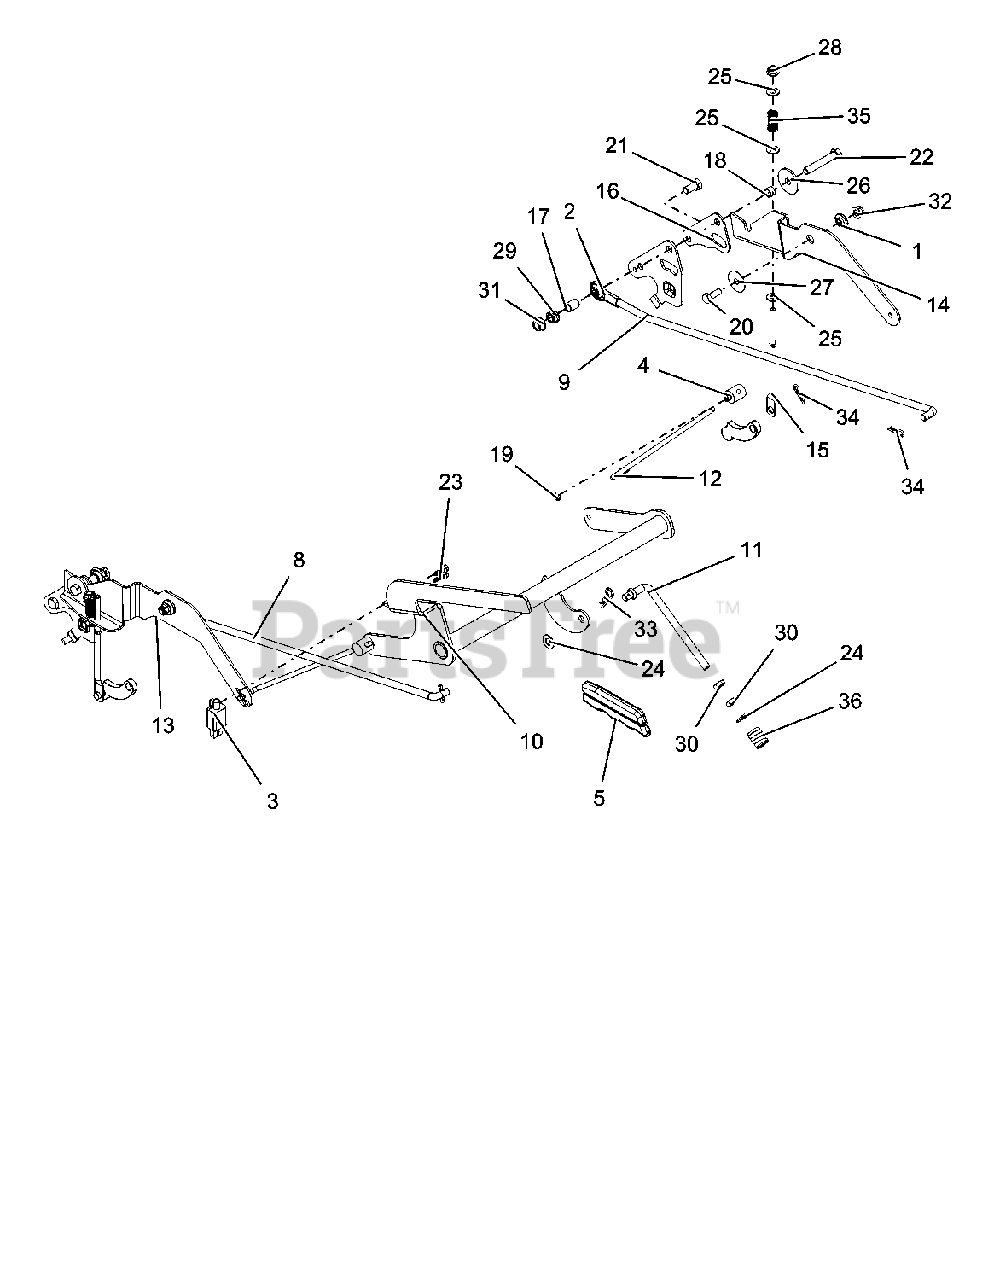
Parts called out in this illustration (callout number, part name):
1	BSHG, FLG .325X.499X.26X.88
2	ROD END, .38 RH
3	SWITCH- DOUBLE POLE N.O./N.O.
4	TRUNION, 1/4-20
5	GRIP, PARKING BRAKE (YELLOW)
8	LINK, RH STEERING
9	ROD, STEERING LINKAGE LH
10	WLDMT, BRAKE LEVER
11	LINK, OVER CENTER BRAKE
12	LINK, BRAKE ARM
13	INTERLOCK, RH BRAKE LINK (BLACK)
14	INTERLOCK, LH BRAKE LINK (BLACK)
15	LINK, BRAKE COG
16	PLATE, TRANSAXLE ADAPTOR
17	SPCR, .385X.500X.652
18	SPCR, .385X.500X.350
19	E-RING, .250 X .025
20	BLT-HEX .31-18X.875 GR5 YWZC
21	BLT-HEX .38-16X.75 GR5 YWZC
22	BLT-HEX .38-16X2.25 GR5 YWZC
23	SCR-TAP #12X.75 BOSS INDHXHD
24	WSHR-FL-STL.406X.812X.065 YWZ
25	WSHR-FL-STL.344X.688X.065YWZC
26	WSHR-FL-STL .380X1.50X.125 YWZC
27	WSHR-FL-STL .347X1.254X.048 YWZC
28	NUT, LK-CTR-FLG .31-18 YWZC
29	NUT, LK-CTR-FLG .38-16 YWZC
30	NUT, JAM .375-16 YWZC
31	NUT, LK-TOP-FLG .38-16 YWZC
32	NUT-LK-NYL-FLG .31-18 YWZC
33	PIN-COTR .09 X 1.50 YWZC
34	PIN, HAIR INT .08X.18X1.18 YWZC
35	SPRG, COMPRESSION
36	SPRG, COMPRESSION
